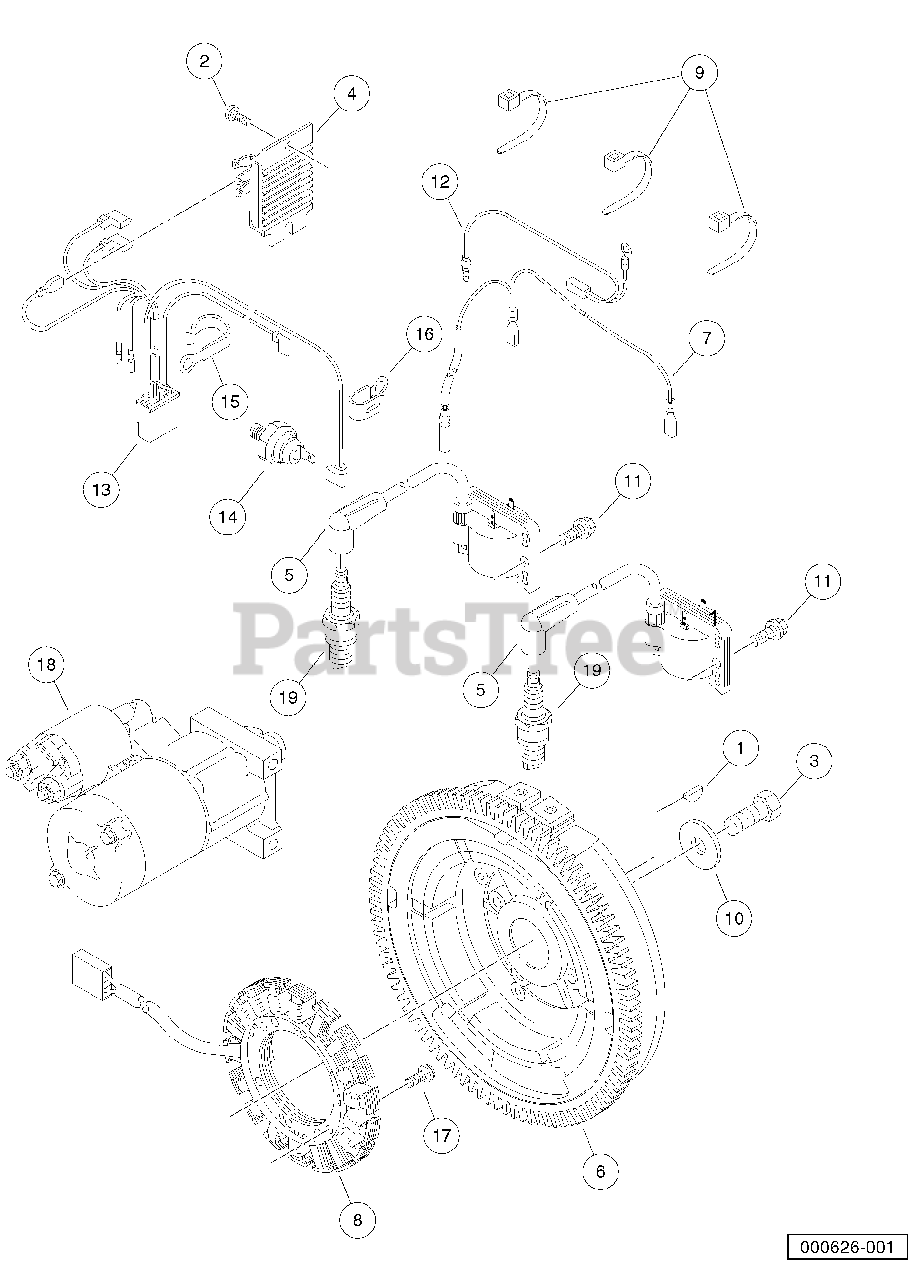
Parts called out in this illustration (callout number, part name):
2	Screw, Pan, Coil Mount, Fh
3	Bolt, Flg, M12 X 1.25 X 30
4	Regulator, Voltage, Fh
5	Coil, Assy, Ignition, Fh
6	Flywheel, Assy, Fh
7	Harness, Regulator, Fh
8	Coil, Charging, Fh
9	Band, Harness, Fh
10	Washer, Flywheel, Fh
11	Bolt, Flanged, M6 X 20, Kaw
12	Harness, Ignition, Fh
13	Harness, Engine, Main, Fh
14	Switch, Oil Pressure, Fh
15	Clamp, Harness, Large, Fh
16	Clamp, Harness, Small, Fh
17	Screw, Pan, Coil Mount, Fh
18	Starter, Electric, Fh680d
19	Spark Plug, BPR2ES
